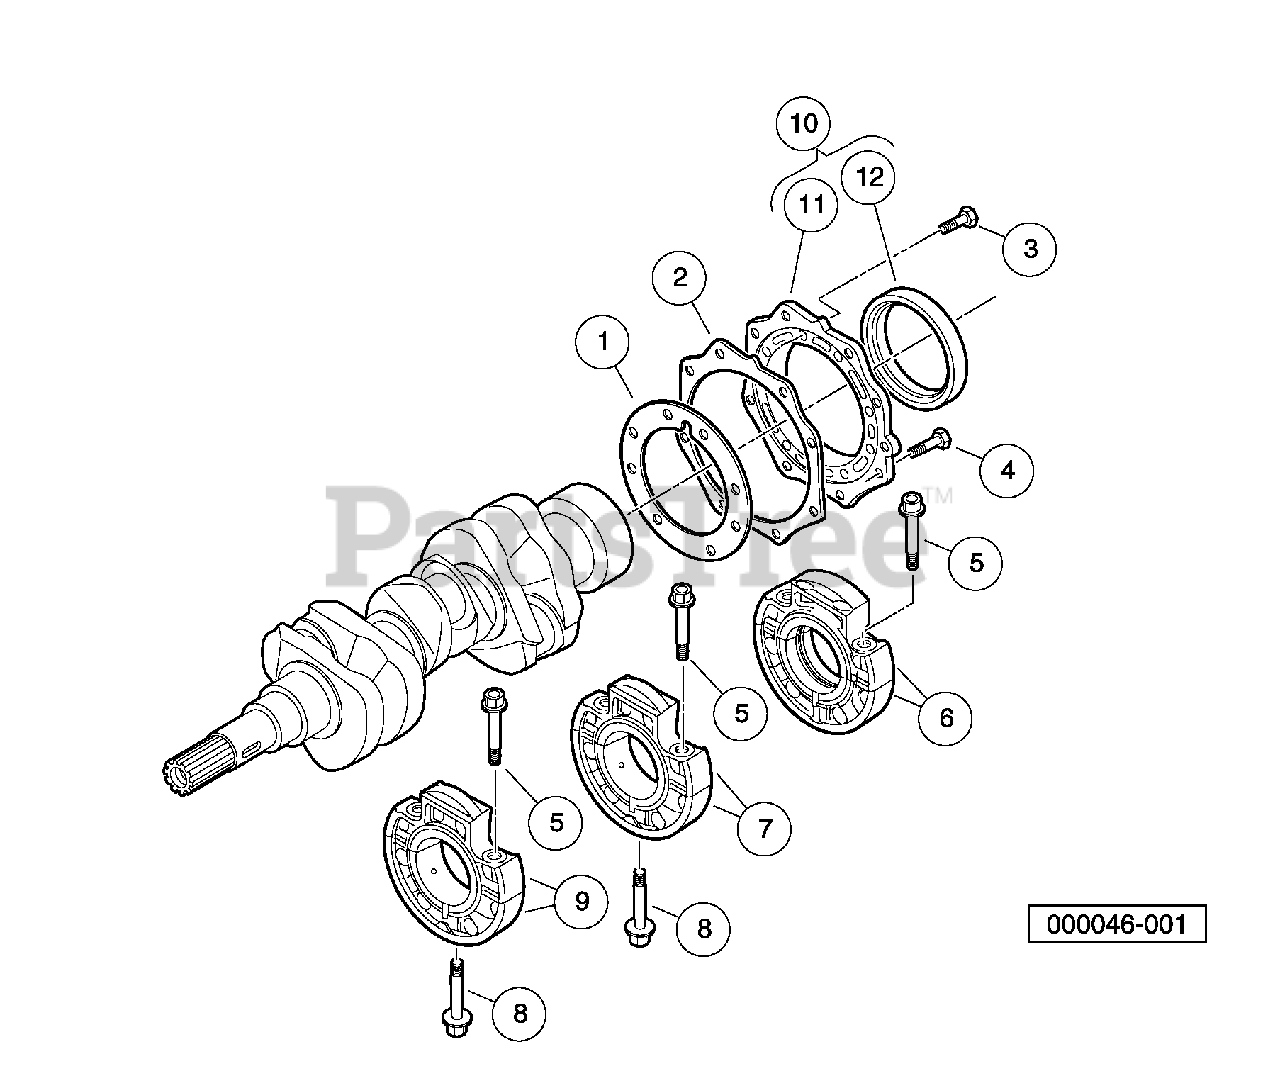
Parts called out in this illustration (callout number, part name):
1	Gasket, Bearing Case
2	Gasket, Cover
3	Bolt, M6 X 1 X 20
4	Bolt, M6 X 1 X 22
5	Bolt, Bearing Case, Top
6	Assy Case, Main Brg, First
7	Assy Case, Main Brg, Sec
8	Bolt, Bearing Case, Bottom
9	Assy Case, Main Brg, Third
10	Assy, Cover, Bearing Case
11	Cover, Bearing Case
12	Seal, Oil.
